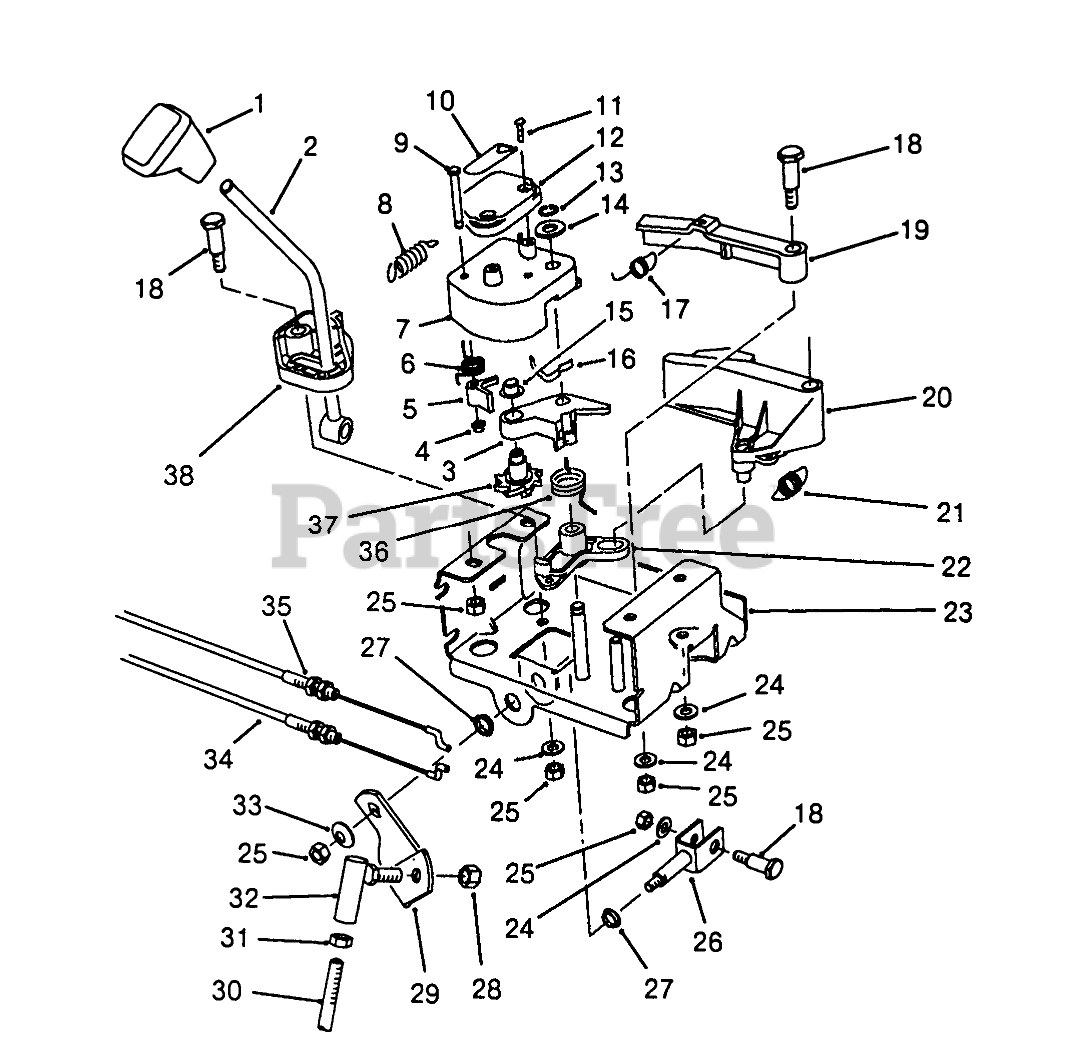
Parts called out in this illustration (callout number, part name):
1	KNOB-SHIFT
2	SHIFT ROD WA
3	LEVER-WHEEL, INDEX
4	NUT-PUSH
5	TANG-INDEX
6	SPRING-TORSION
7	LATCH-LEVER
8	SPRING-EXTENSION
9	PIN-TANG
10	DECAL
11	SCREW-PPH
12	COVER-LATCH
13	RING-RETAINING
14	WASHER-THRUST
15	RETAINER-PUSH ON
16	SPRING-FLAT
17	SPRING-EXTENSION
18	SCREW-SHOULDER
19	LEVER-LOCKOUT
20	LEVER-REVERSE
21	SPRING-EXTENSION
22	LEVER-REVERSE, SWITCH
23	Frame-Control
24	WASHER-PLAIN
25	NUT-LOCK, NI
26	CLEVIS WA
27	BUSHING
28	NUT-LOCK
29	BRACKET-SHIFT
30	ROD-BENT SHIFT, LOWER
31	NUT-HJ
32	JOINT-BALL
33	WASHER-BELLEVILLE
34	CABLE-GEARBOX
35	CABLE-ARM, LATCH
36	SPRING-TORSION
37	WHEEL-INDEX
38	BASE-LOCKOUT
